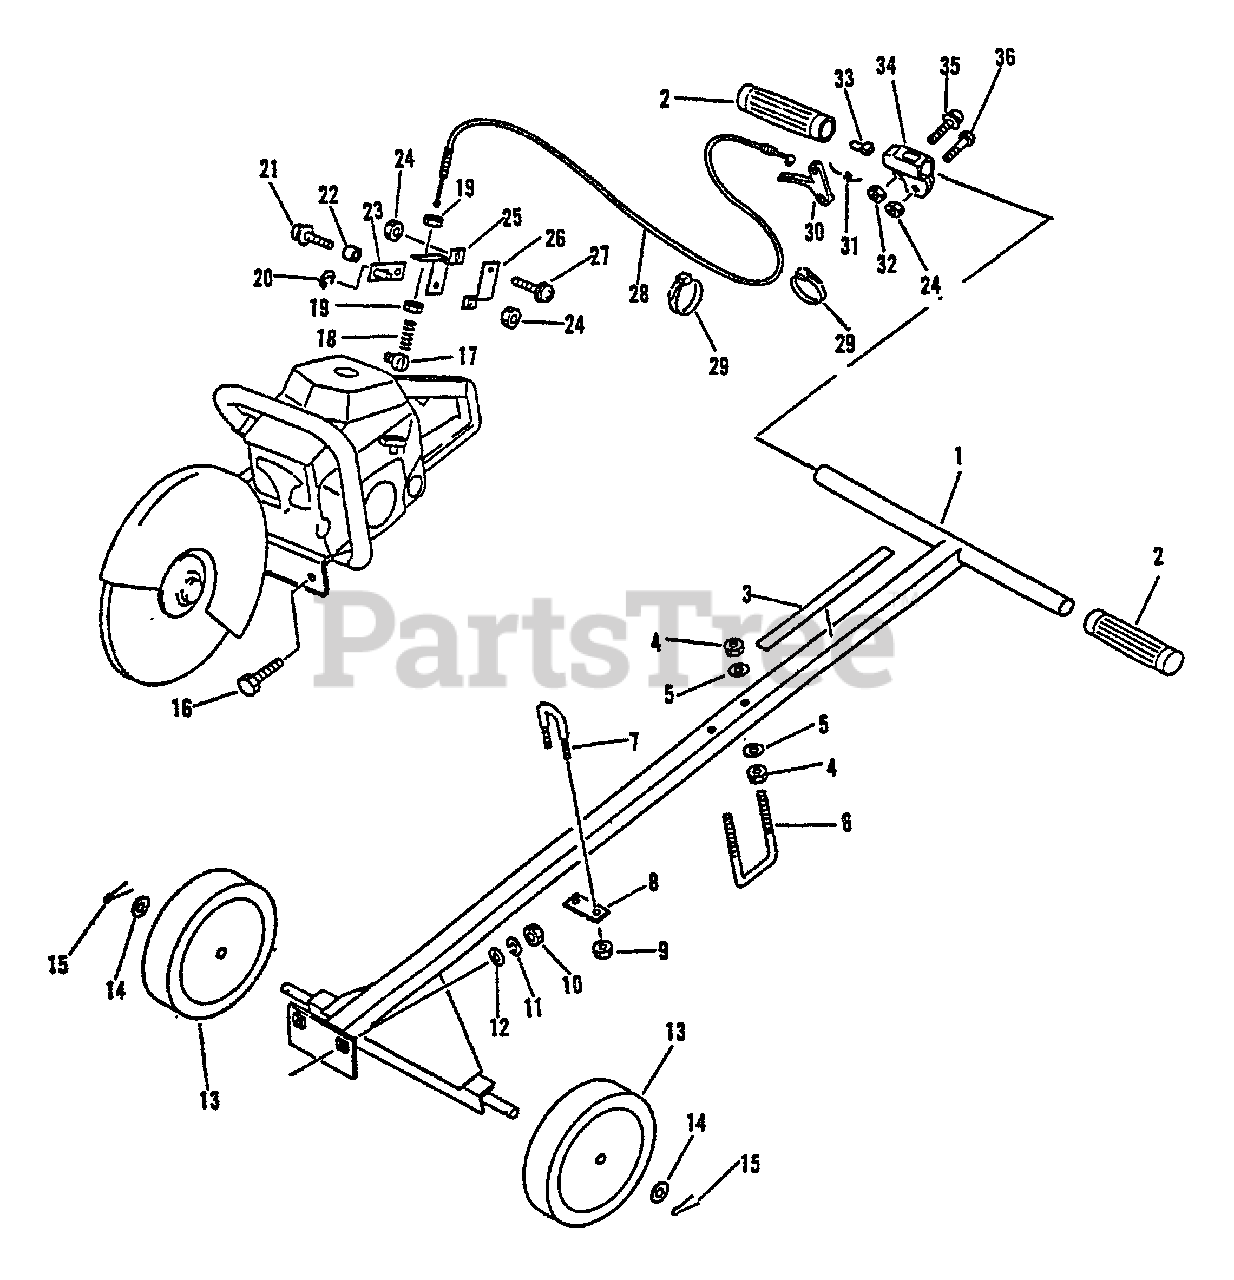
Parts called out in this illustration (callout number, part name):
1	CART
2	GRIP, HANDLE
3	LABEL - CAUTION
4	3/8" - 16 NUT
5	WASHER - 3/8"
6	SQUARE BEND U-BOLT, LEG WIDTH 2", LENGTH 5"
7	U-BOLT, 1" PIPE, 1/4 - 20 THREAD
8	PLATE
9	NUT - 1/4-20
10	NUT - 5/16-18
11	LOCKWASHER - 5/16"
12	WASHER - 5/16"
13	WHEEL
14	WASHER - 1/2"
15	PIN, SPLIT - 2X22
16	SCREW - 5/16" X 18 X 1"
18	SPRING, TRIGGER
20	RING, RETAINING - 4
21	SCREW - 5X22
23	TRIGGER, THROTTLE
24	LOCKNUT - 5
25	BRACKET
26	TRIGGER, MOUNTING BRACKET
27	SCREW - 5X16
28	CABLE, THROTTLE
29	TIE, CABLE
30	TRIGGER, THROTTLE
31	SPRING, TRIGGER
33	GUIDE, CABLE
34	BRACKET, TRIGGER
35	SCREW - 5X35
36	SCREW - 5X30
